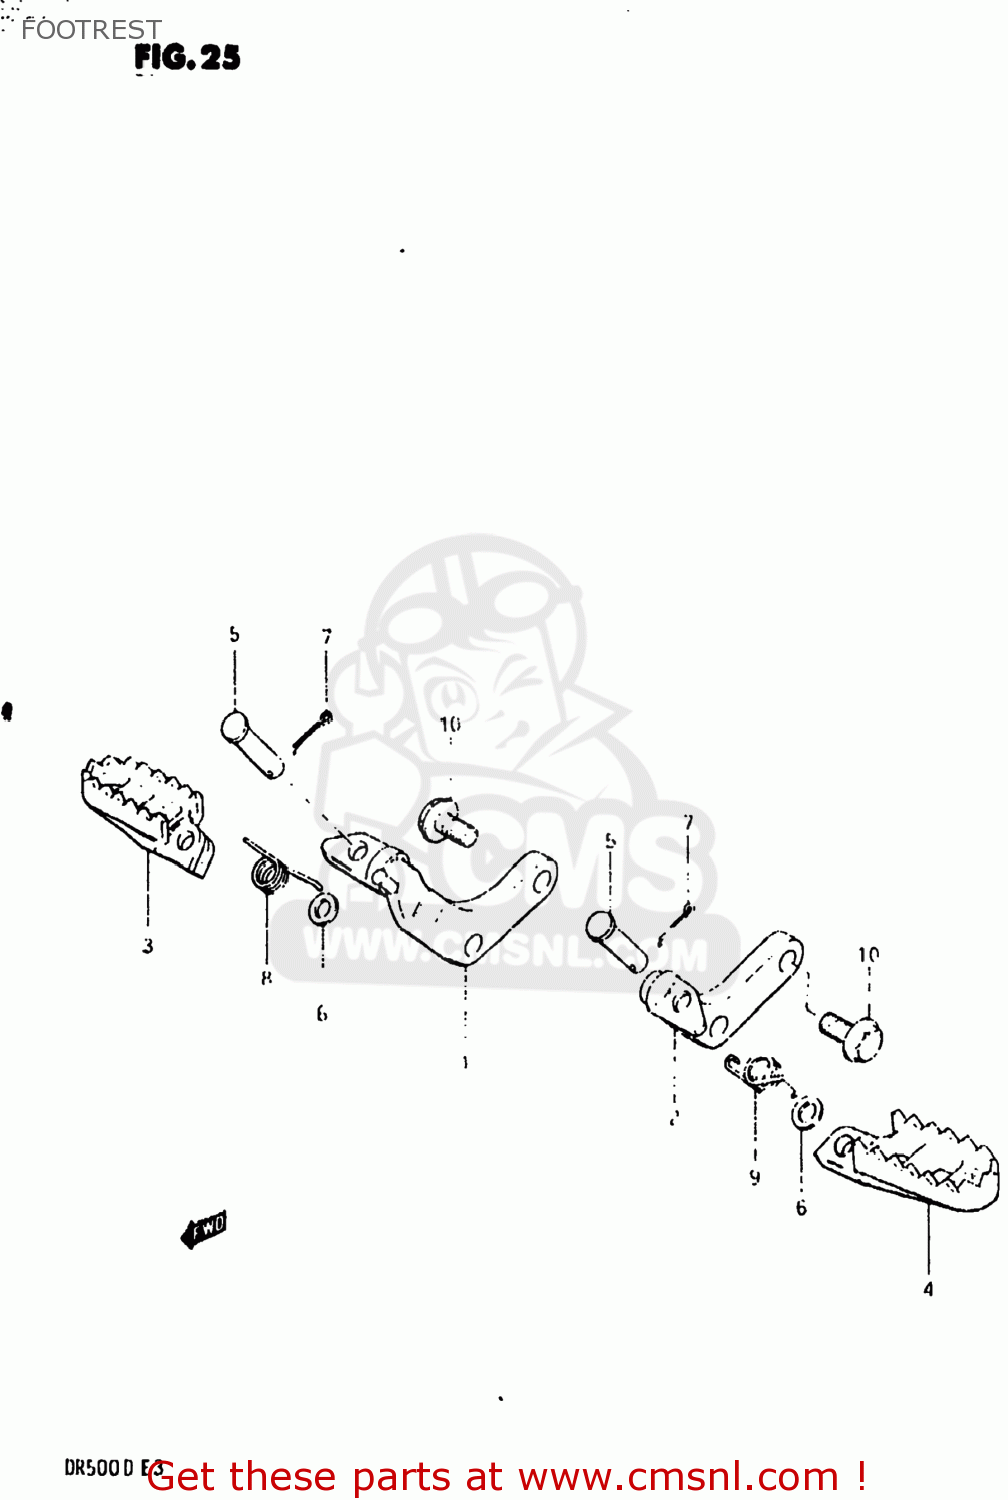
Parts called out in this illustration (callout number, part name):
1	BAR,FRONT FOOTREST
2	BAR,FRONT FOOTREST,LEFT
3	FOOTREST,RIGHT
4	FOOTREST
5	PIN
6	WASHER
7	PIN 20X20
8	SPRING
9	SPRING
10	BOLT(10X25)
